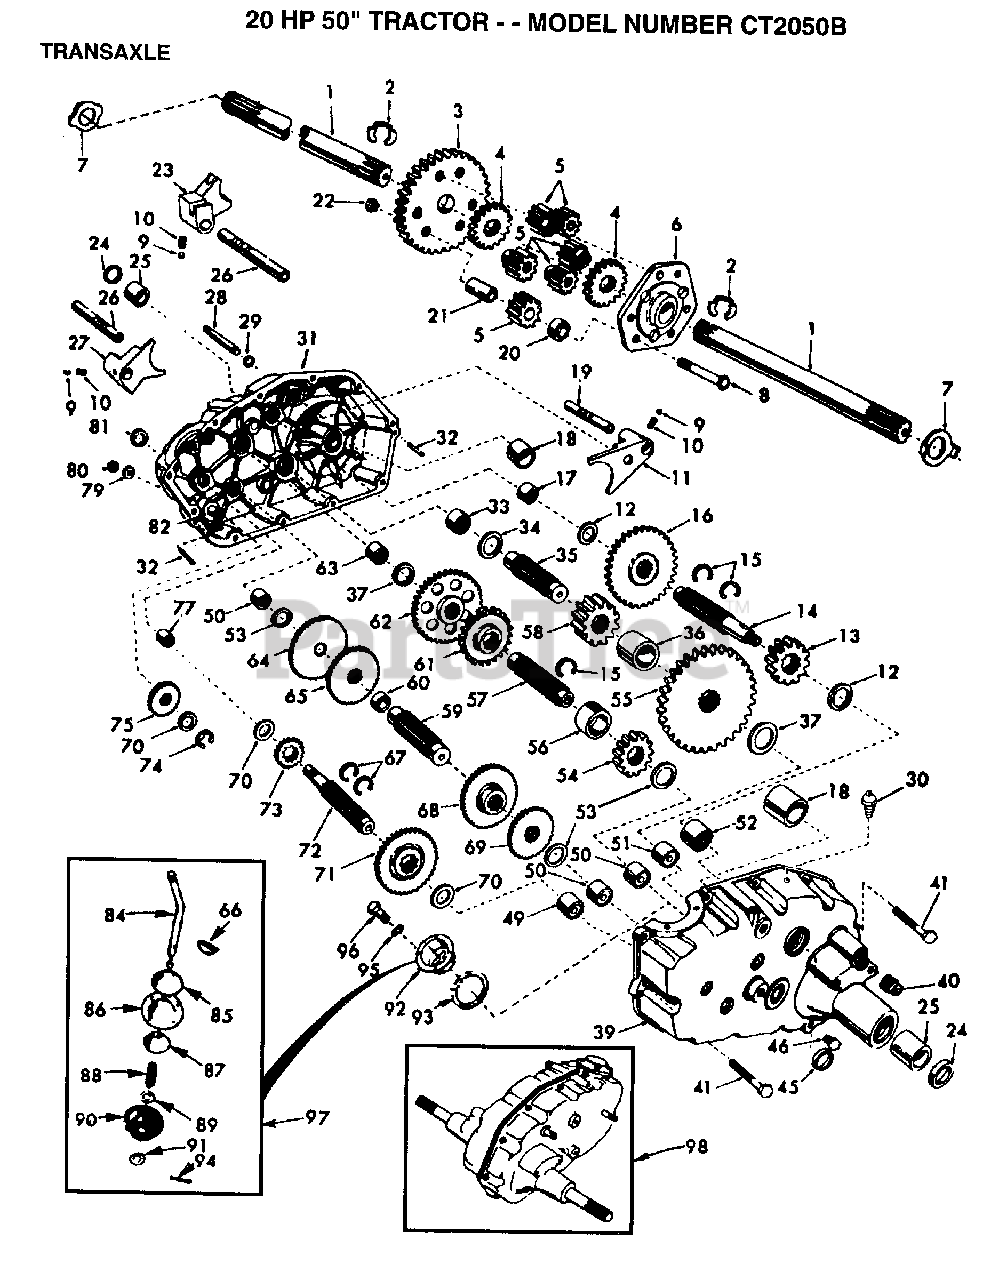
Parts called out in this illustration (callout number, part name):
1	SHAFT.AXLE.T
2	KLIP RING
3	FINAL GEAR T
4	DIFF GEAR T
5	DIFF PINION T
6	DIFF CARRIER T
8	BOLT
11	SHIFT FORK T
12	WASHER .T
13	RED PINION T
14	SHAFT BRAKE GT
15	SNAP RING T
16	GEAR T
17	"T, BEARING"
18	BEARING
19	SHAFT
20	SPACER T
21	PINION RS
22	GRIPCO NUT
23	FORK T
24	OIL SEAL STD
25	BRNG. T
26	SHIFT FORK SHAFT
27	SHIFT FORK T
28	SHIFT SHAFT
29	SEAL T
30	VALVE M
31	GEARCASE RH W/BER
32	PIN T
33	NEEDLE BRNG T
34	RACE T
35	GEAR SHAFT T
37	RACE T
39	GEARCASE LH W/BER
40	PLUG PIPE
41	BOLT.5/16-18X1.25
45	SEAL T
49	"TI, BEARING"
50	NEEDLE BRNG T
51	NEEDLE BRNG T
52	"STD, BEARING"
53	BRNG RACE
54	RED PINION T
55	RED GEAR T
56	PINION SPACER T
57	GEAR SHAFT T
58	FINAL PINION T
59	GEAR SHAFT T
60	SPACER T
61	RED PINION T
62	RED GEAR T
63	RACE T
64	LOW SPEED GEA T
65	REVERSE GEAR T
66	KEY T
67	KLIP RING
68	INTERMED GEAR T
70	"T, BEARING"
71	CLUSTER GEAR T
72	SHAFT INPUT
73	LO SPEED PINION T
74	KLIP RING
75	IDLER GEAR T
77	NEEDLE BEARING TI
79	WASHER T
80	NUT
81	SEAL STD
82	SHAFT REVERSE IDL
84	GEAR SHIFT LVR T
85	CAP T
86	COVER AND PIN T
87	GUIDE BALL T
88	SPRING TI
89	WASHER
90	SEAL T
91	WASHER
92	GEAR SHIFT GA T
93	GASKET T
94	COTTER PIN
95	LOCKWASHER
96	BOLT
97	GEAR SHFT LVR T
